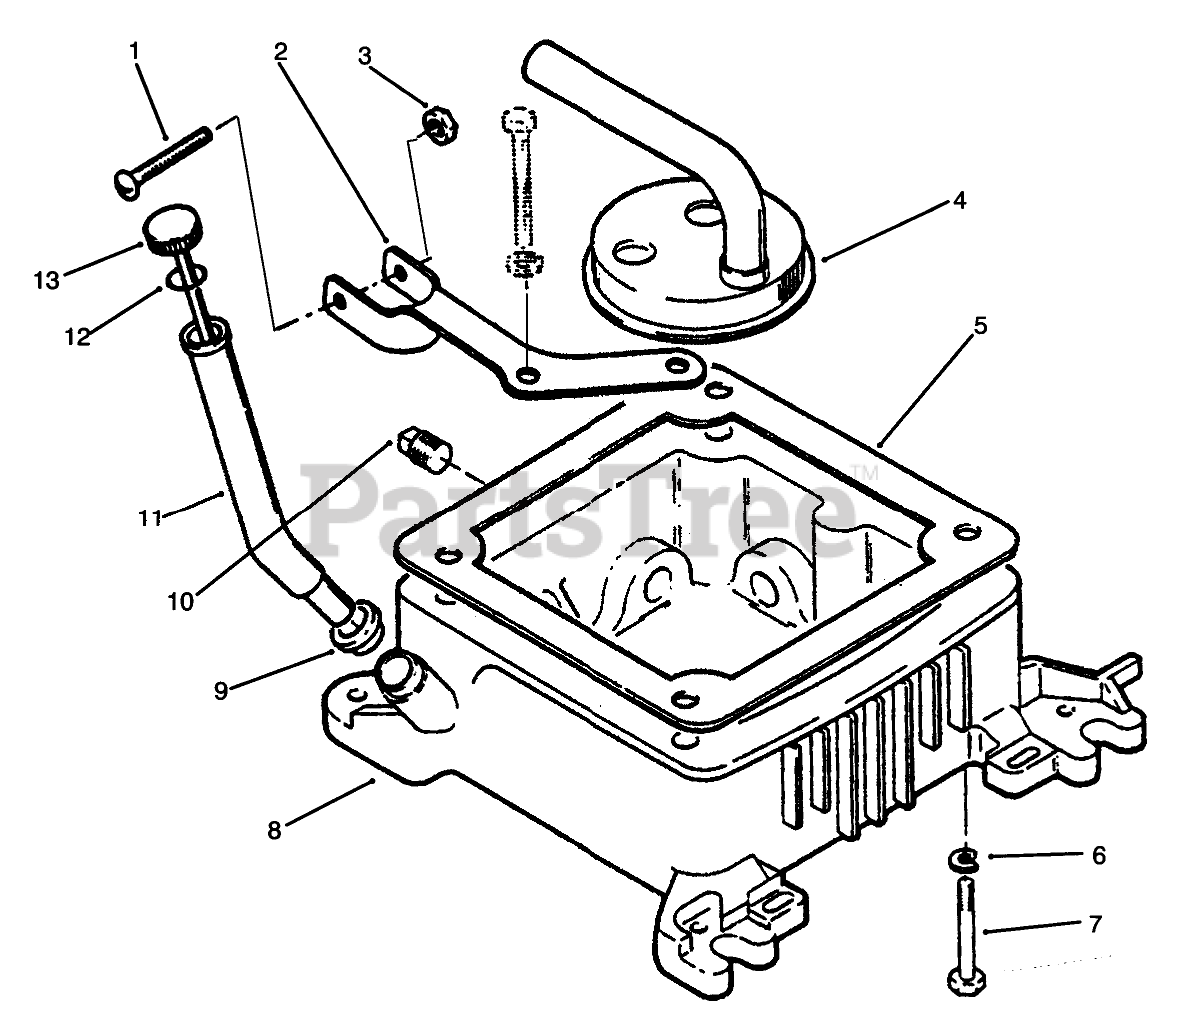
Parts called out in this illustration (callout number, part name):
1	SCREW - PAN HEAD
2	BRACKET-FILL TUBE
3	NUT - SPEED
4	OIL CUP ASM
5	GASKET
6	WASHER-FLAT
7	HHCS 3/8-16 X 3 3/4
8	Base-Oil (Incl. Ref. #10)
9	SEAL-OIL FILL TUBE
10	PLUG - SQUARE HEAD
11	Tube-Oil Fill
12	SEAL 0-RING
13	Cap & Indicator-Oil Fill (Incl. Ref. #12)
